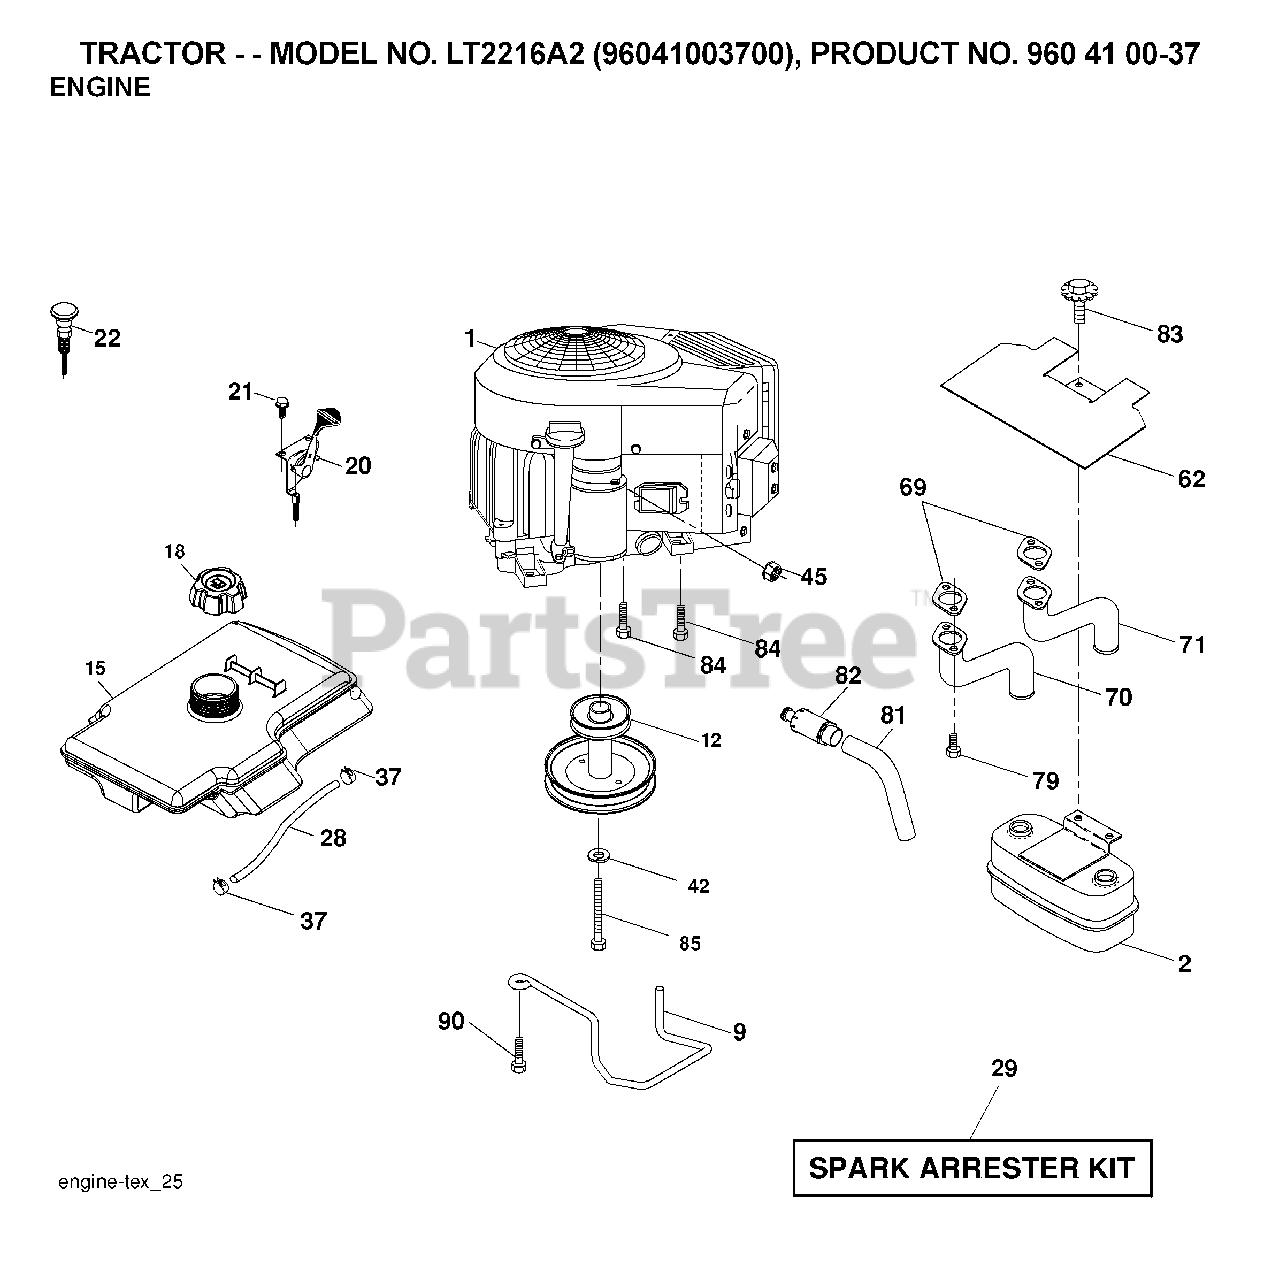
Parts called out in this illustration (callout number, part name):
9	KEEPER.BELT.ENGINE.4.2
12	PULLY ENGINE
18	CAP.ASM.FUEL.TANK.3"BL
20	THROTTLE CABLE
21	SCREW
22	CONTROL CHOKE
29	ARRESTER SPARK (OPTIONAL)
37	HOSE CLAMP
42	LOCKWASHER
45	NUT
62	RP SHIELD HEAT MUFFLER
69	GASKET.MUFFLER
70	TUBE MANIFOLD LH
71	EXHAUST TUBE RH
79	SCREW.SOCKET.HEAD.5/16-18
81	TUBE, DRAIN OIL ASM.
82	PLUG DRAIN OIL EASY
83	BOLT, 5/16-18 X 1 3/4
84	SCREW.3/8-16
85	BOLT HEX 7/16-20X4-1/4"
90	SCREW 3/8-16X1
